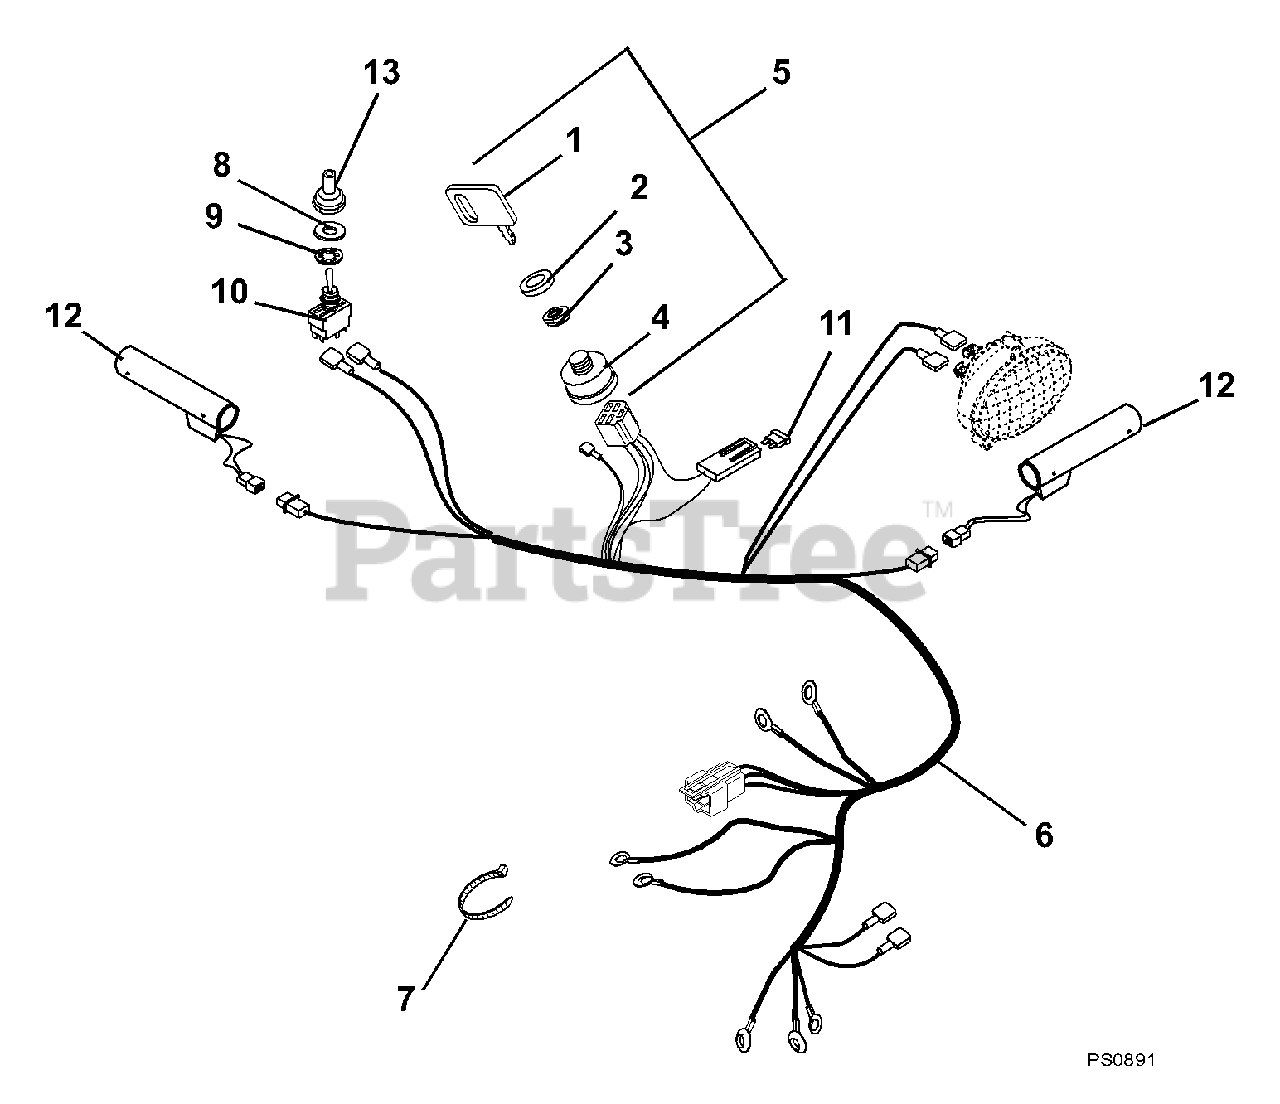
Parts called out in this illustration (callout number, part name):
1	KEY -W/CAP
2	CAP - IGNITION SWITCH
3	NUT-PANEL .625-32 GRECO
4	IGNITION SWITCH ASSEMBLY
5	SWITCH ASSEMBLY
6	HARNESS, WIRE-LIGHT HANDWARMER
6	HARNESS, WIRE-LT, HW, 12V
7	CABLE TIE LG 5-1/2
8	WSHR-FL-STL .505X.875X.024 PL
9	WSHR-LK-INT .563X.040 YWZC
10	SWITCH, ON/OFF
11	FUSE, 15 AMP.
12	WARMER, HAND W/TERMINAL
13	BOOT, SWITCH
